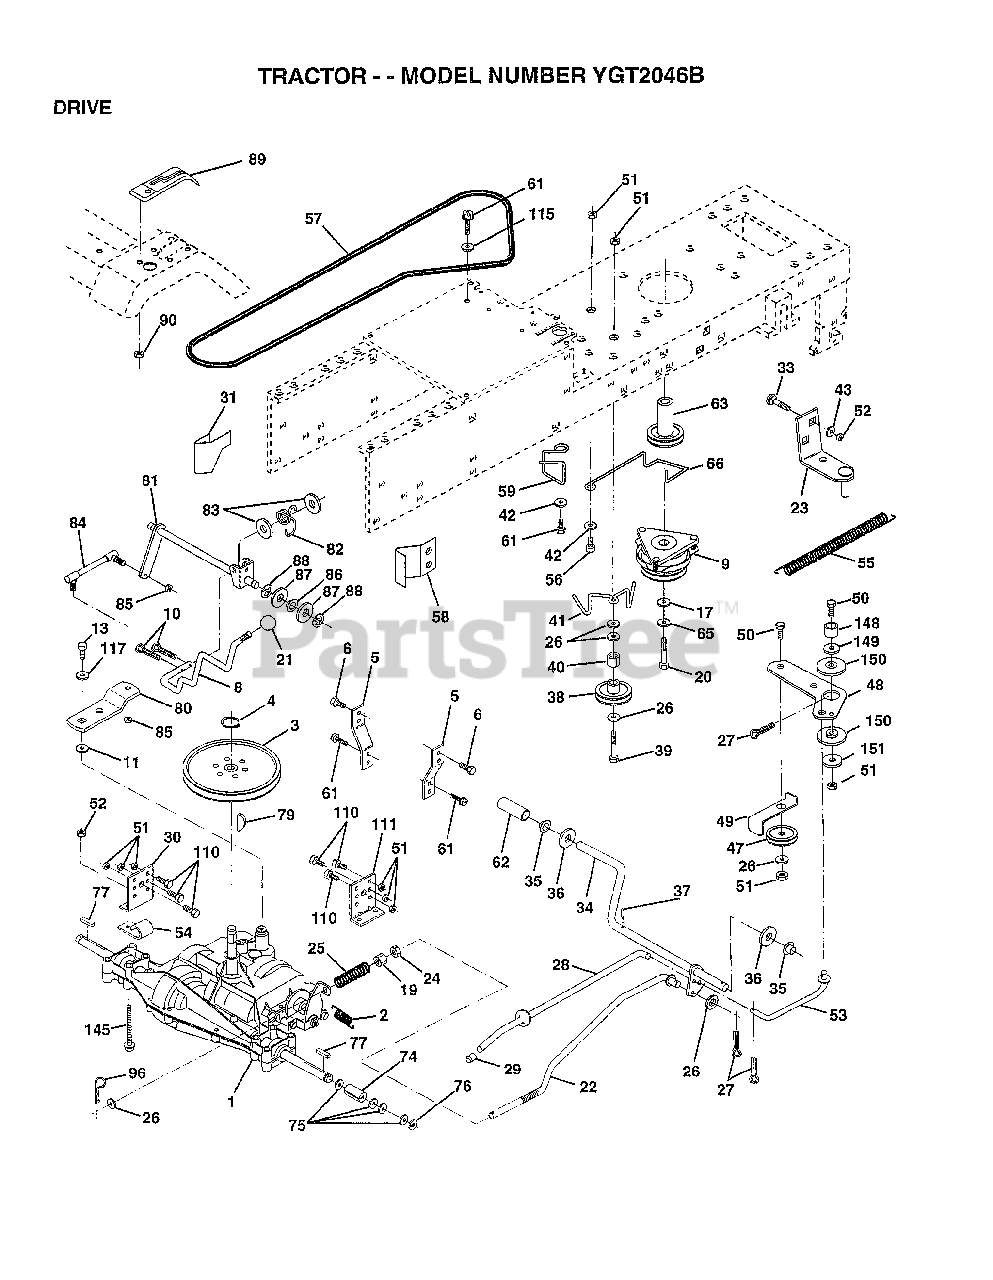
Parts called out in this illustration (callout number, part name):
3	PULLEY TRANSAXLE
4	RING
5	STRAP TORQUE
6	SCREW
8	ROD SHIFT FEND YT
10	PIN COTTER 1/8
11	WASH-SHFT PLT LT
13	BOLT.1/4-28.W/PAT
17	WASHER
19	NUT
20	BOLT.7/16-20X4.25
21	KNOB.DUCKHEAD.1/2
22	ROD.ASM.BK.44.MWR
23	BRACKET.ASM.MTG
24	NUT
25	"SPRING,ROD BRAKE"
26	WASHER
27	COTTER PIN
28	ROD.BRAKE.PARK.LT
29	PLUNGER CAP T
30	BRKT TRANS LH
31	KEEPER BELT LH
33	BOLT
34	SHAFT ASM-PEDAL F
35	NYLON BEARING
36	WASHER LT
38	PULLEY.IDLER.FLAT
39	BOLT
40	SPACER T
42	WASHER
43	WASHER T
48	BELLCRANK ASM
49	RETAIN BELT
53	"LINK, CLUTCH T"
54	"CLIP,INSULATOR"
55	"SPRING, RETURN LT"
57	BELT.GRDRV.94.75
58	"KEEPER,BELT RH"
59	KEEPER BELT CNTSP
61	SCREW
62	"COVER,PEDAL"
63	"PULLEY, ENGINE"
65	LOCKWASHER
66	KEEPER-BELT
74	SPACER HYT
75	WASHER
76	E RING HYT
77	SQ KEY STD
80	"ARM,SHIFT"
81	SHAFT ASM CROSS
82	"SPRING,TORSION"
83	WASHER
84	"ROD LINK,SHIFT AD"
85	NUT.CNT.LOCK.1/4
86	BUSHING
87	WASHER D
88	KLIP RING
89	CONSOLE SHIFTER
90	NUT
111	BRKT TRANS RH
115	WASHER GT
117	WASHER PM
145	BOLT.HEX.FLGHD
149	SPACER RETAINER
150	BUSHING.NYLON
151	WASHER
